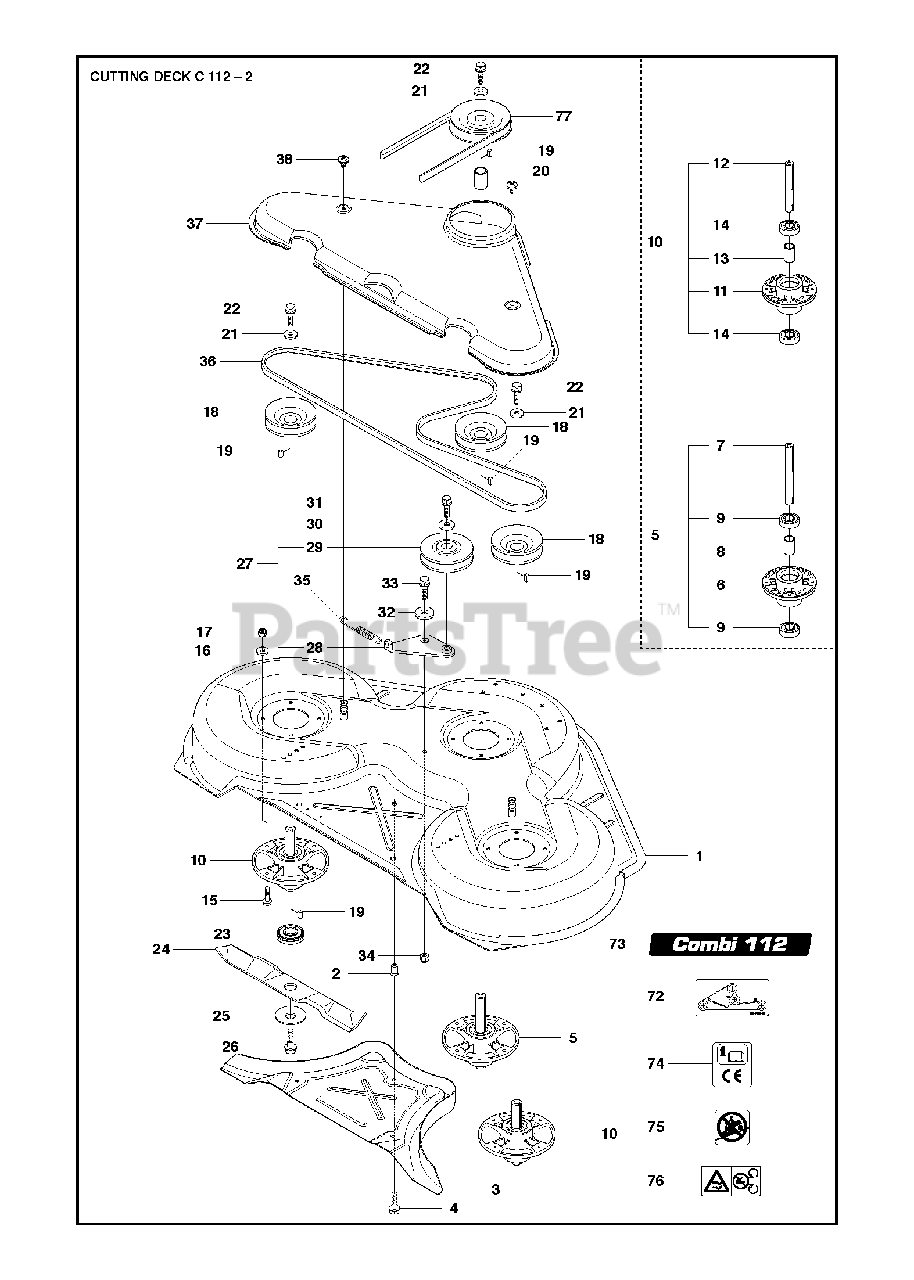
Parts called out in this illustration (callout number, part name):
1	CUTTING DECK
5	BLADE HOUSING ASSY
6	BEARING HOUSING
7	SHAFT
8	SPACING SLEEVE
9	BEARING
10	BLADE HOUSING ASSY
11	BEARING HOUSING
12	SHAFT
13	SPACING SLEEVE
14	BEARING
16	WASHER BRB 8.4X17
17	LOCKNUT M8
25	WASHER
29	PULLEY
30	SPACER
32	WASHER
34	LOCKNUT M8
36	BELT
37	BELT COVER
